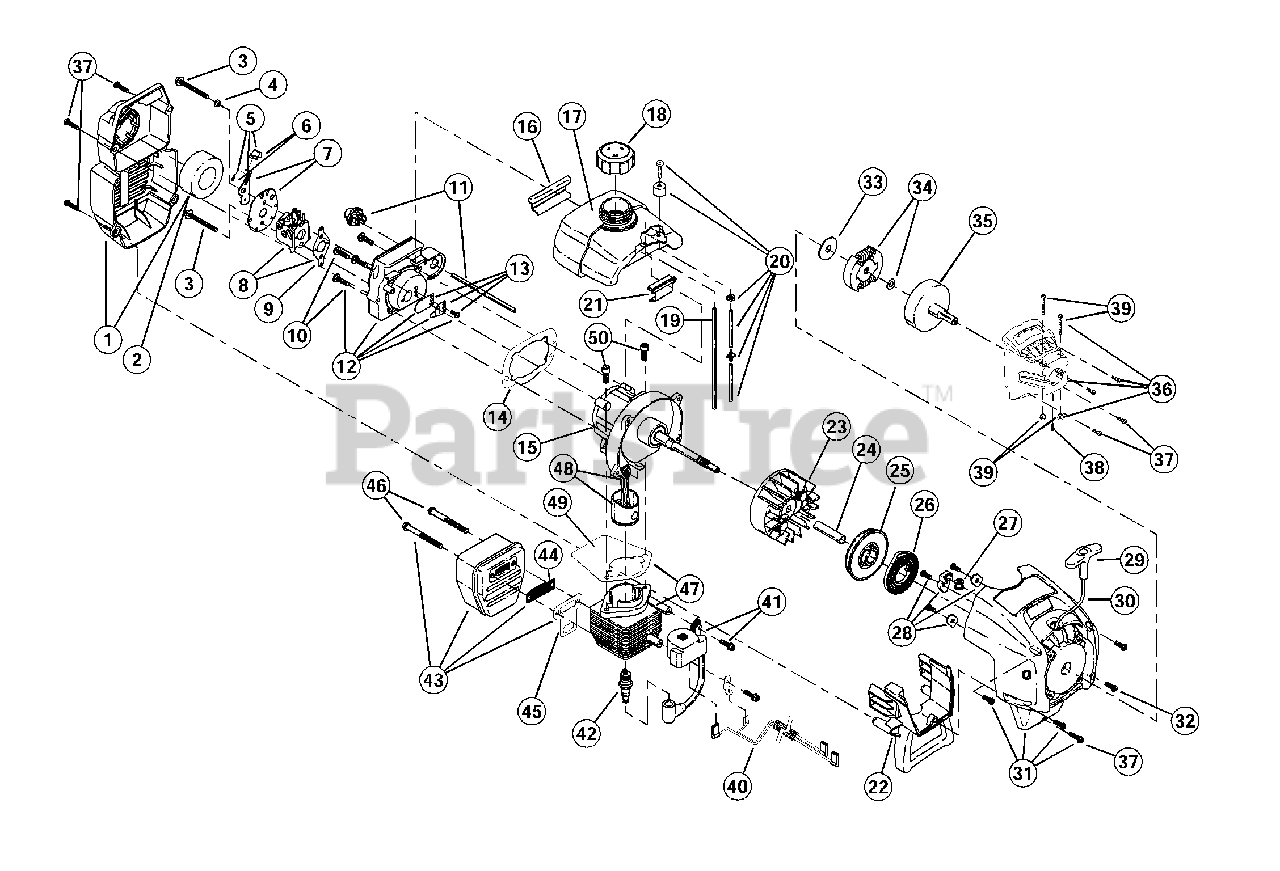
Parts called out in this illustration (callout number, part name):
1	Air Cleaner/Muffler Cover Assembly
2	Air Cleaner Filter
3	Carburetor Mounting Screw Assembly
4	Wavey Washer
5	Choke Lever Assembly
6	Choke Knob and Screw
7	Choke Lever and Plate
8	Carburetor Assembly
9	Carburetor Gasket
10	Carb Mount Screw
11	Primer and Hose Assembly
12	Carb Mount Assembly
13	Reed Assembly
14	Crankcase Gasket
15	Crank Case Service Assembly
16	Rear Mounting Pad
17	Fuel Tank Assembly
18	Fuel Cap Assembly
19	Fuel Return Line
20	Fuel Line Assembly
21	Front Mounting Pad
22	Shroud Extension and Stand
23	Flywheel Assembly
25	Recoil Pulley Assembly
26	Recoil Spring
27	Rope Guide
28	Pulley Retainer Assembly
29	Pull Handle
31	Starter Housing Assembly
32	Housing Screw
33	Clutch Washer
34	Clutch Rotor Assembly
35	Clutch Drum Assembly
36	Clutch Cover Assembly
37	Cover Screw
38	Anti-Rotation Screw
39	Clamping Screw
40	Wire Leads and Sleeve
41	Module Assembly
42	Spark Plug
43	Muffler Assembly
44	Spark Arrestor Screen
45	Exhaust Gasket
46	Muffler Mounting Bolt
47	Cylinder Assembly
48	Piston and Rod Assembly
49	Cylinder Gasket
50	Cylinder Bolt
